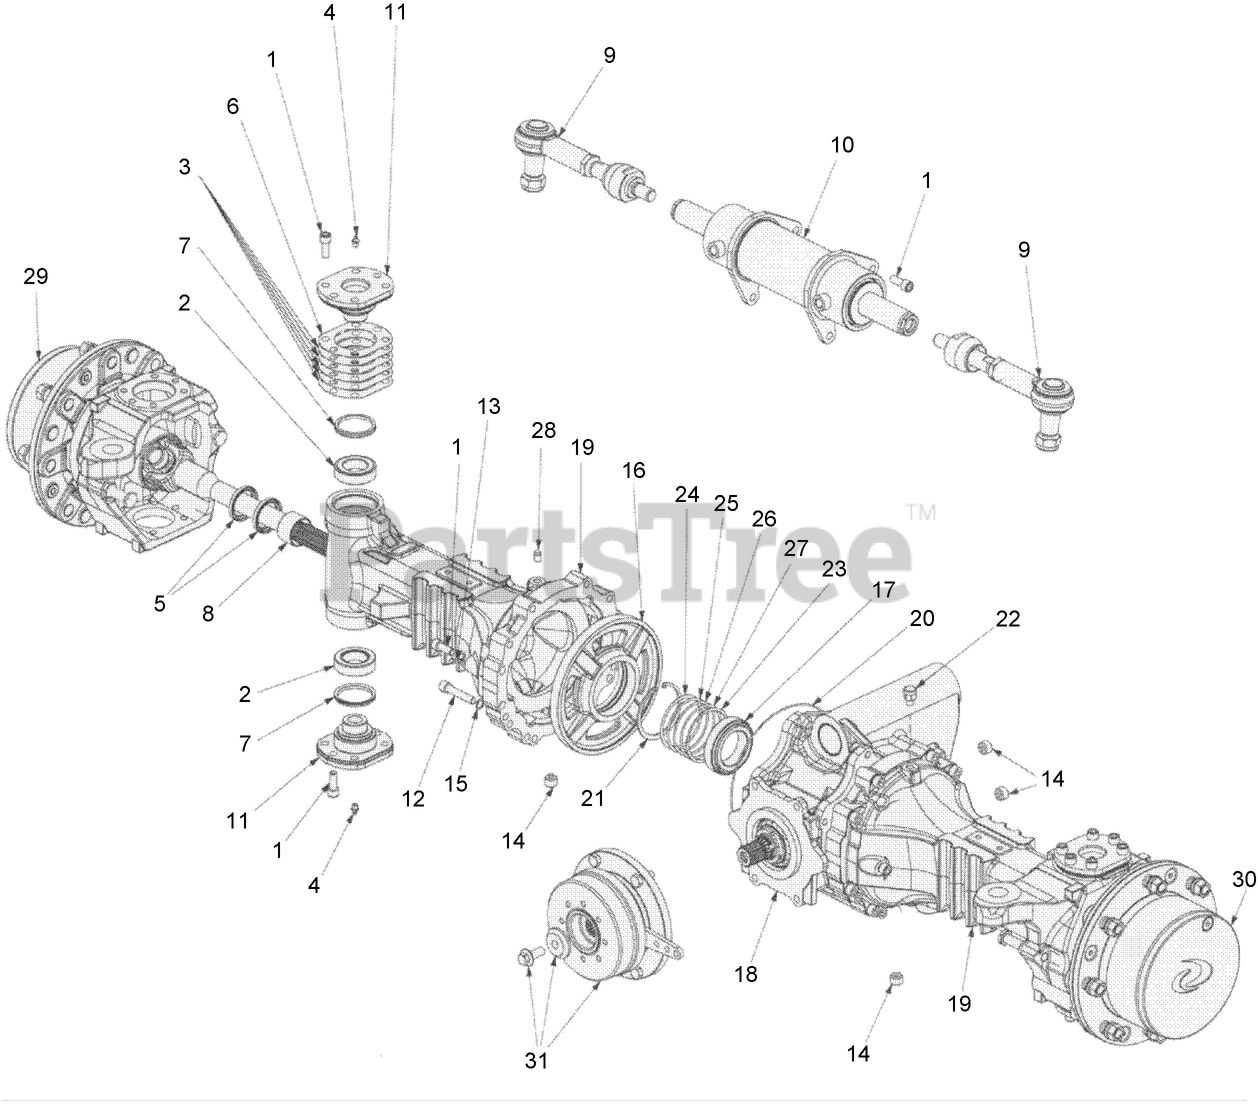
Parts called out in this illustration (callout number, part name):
2	JOINT-BALL
4	JOINT-Lube
7	V-RING
8	Bushing
9	Rod-Tie
10	Cylinder-Steering
11	PIN-Flagged
15	Washer
16	FLANGE-Differential
17	Bearing
19	HOUSING-Side
20	O-RING
21	RING-SNAP
22	PLUG-Oil Filter
29	GROUP-Wheel Hub
30	GROUP-Wheel Hub
